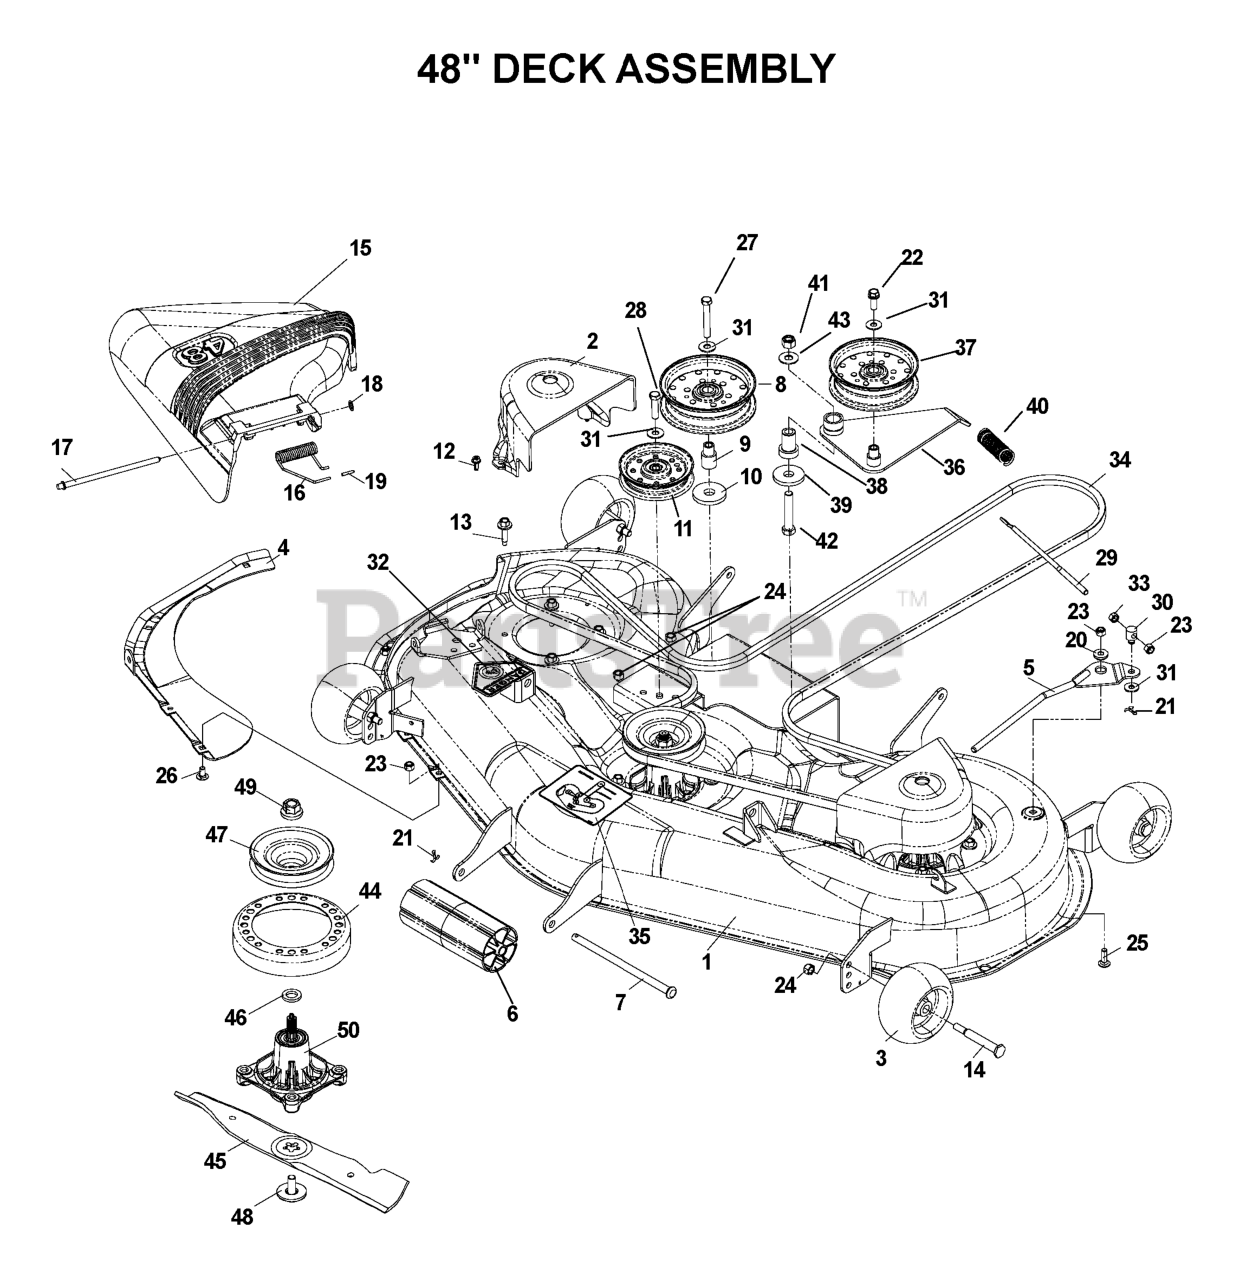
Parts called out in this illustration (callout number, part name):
1	DECK W/DECALS 48" HUS
2	BELT SHIELD
3	GAUGE WHEEL
4	VORTEX MOWER BAFFLE
5	TENSION RELIEF LEVER BLK
6	NOSE ROLLER-48"
7	NOSE ROLLER ROD
8	IDLER PULLEY
9	IDLER BUSHING
10	WASHER, SUPPORT
11	FLAT IDLER PULLEY
12	SCREW- 1/4-20 X 5/8
13	WASHER HEAD SCREW
14	SHOULDER BOLT 1/2X2-5/8 ZD SPE
15	DISCHARGE CHUTE
16	TORSION SPRING
17	ROD, HINGE
18	PUSH NUT
19	CAP-SLEEVE
20	PIVOT BUSHING
21	RP_COTTER PIN 1/8 X 3/4
22	4CS 3/8C X 1 SERRATED HEAD
23	NUT 5/16 NYLOC
24	NUT 3/8-16 NYLOC
25	RHSNB 5/16C X 1
26	CARRIAGE BOLT 5/16C X 5/8"
27	SCREW 3/8C X 2 3/4 HEX CAP
28	HCS 3/8-16 X 1 3/4 GR5
29	TENSION RELIEF LINKAGE
31	WASHER 5/16 FLAT
32	DECAL, CPSC
33	NUT 5/16C HEX
34	BELT, DECK
35	DECAL, BELT ROUTING
36	DECK IDLER ARM WELDMENT
37	IDLER PULLEY
38	IDLER SPINDLE
39	SUPPORT PLATE
41	NUT 1/2-13 HEX NYLOC ZD
42	SCREW, 1/2C X 3 HEX CAP
43	WASHER 1/2 FLAT
44	STRIPPER-ROUND-UNIVERSAL
45	BLADE-HIGH LIFT/48"
46	WASHER-SPACER
47	DRIVEN PULLEY-48"
48	BLADE BOLT ASSY-7/16" TB REPL
49	LOCKNUT - 9/16
50	CUTTER HOUSING
